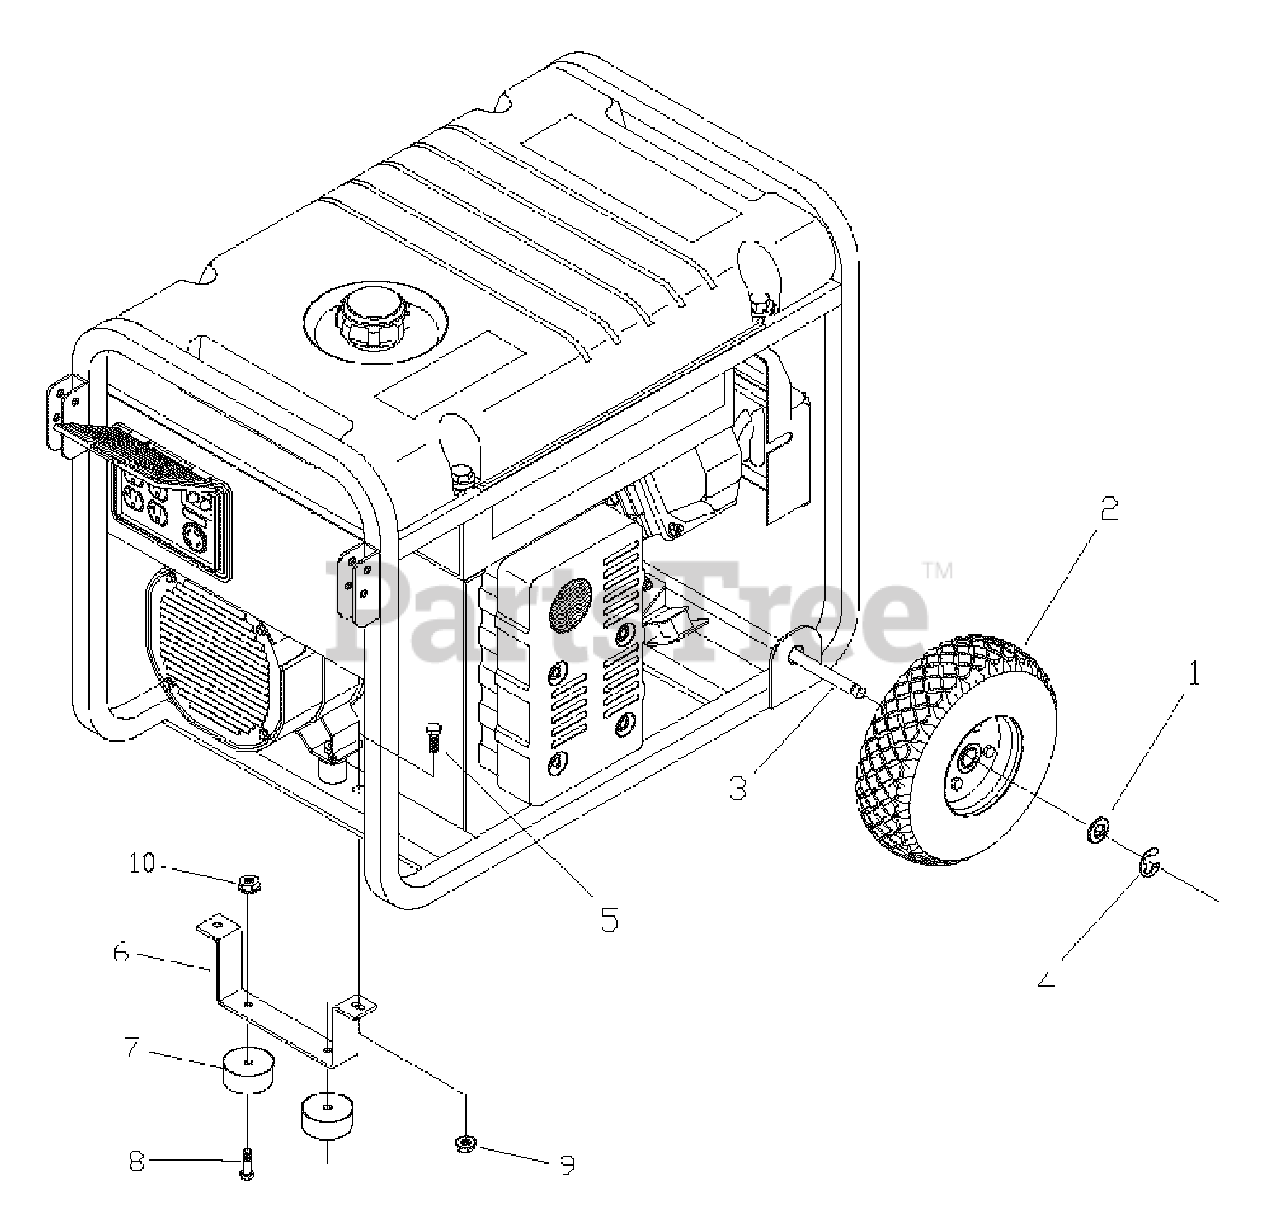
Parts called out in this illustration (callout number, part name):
1	WASHER
2	WHEEL
4	E-RING
5	SCREW
6	LEG, Support
7	VIBE MOUNT, with Washer
8	SCREW
9	NUT, Lock
10	NUT, Lock
